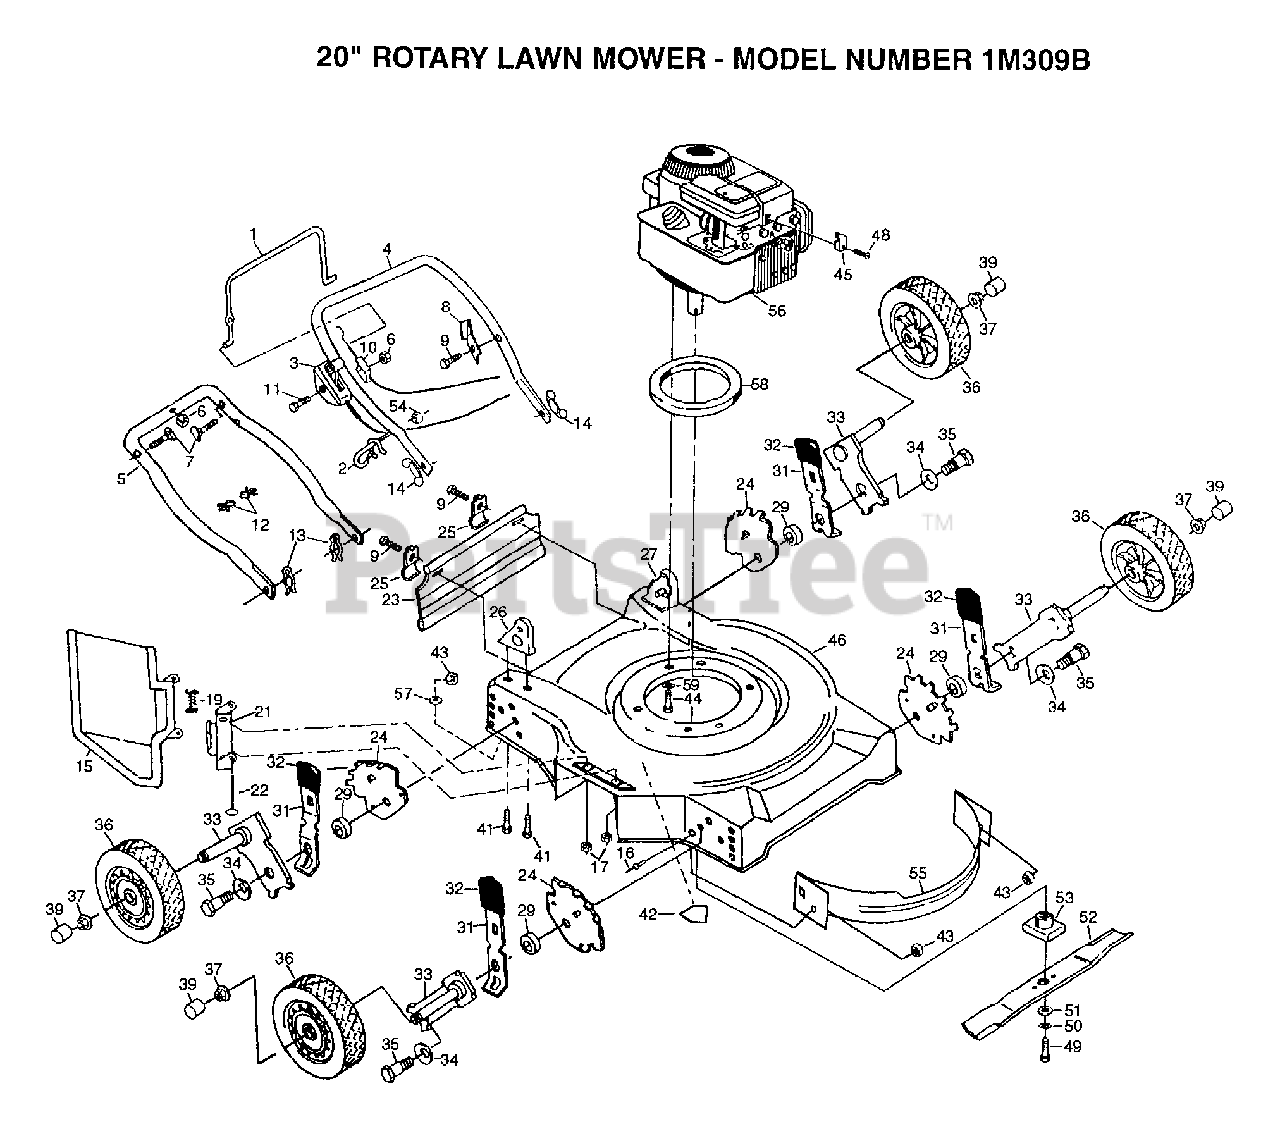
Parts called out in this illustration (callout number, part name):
1	CONTROL BAR PM
2	ROPE GUIDE
3	"CONTROL, THROTTLE"
7	BOLT.HANDLE.LM
8	"BRKT,UPSTOP"
9	TAPPING SCREW
10	CABLE.ASM
11	SCREW.HXHD.WASH.
13	HAIRPIN COTTER
14	"NUT,WING PM"
15	"GRD,DISCHARGE"
16	BLIND RIVET
19	"SPRING,TORSION"
21	HINGE DEFLECTOR
22	HINGE ROD
23	SKIRT.RD.20/22
24	BRACKET.ADJ.9POS.
25	"BRKT,DEFL PM"
26	HDLE BRKT ASSY.RH
27	HDLE BRKT ASSY LH
29	SPACER.HEIGHT.ADJ
31	SPRING SELECTOR
32	KNOB PM
33	ARM.AXLE.ASM.BZP.
34	"WASHER, BELLEVIL."
35	BOLT SHLD 3/8-16
36	WHEEL&TIRE
37	HEX FLANGE LOCKNT
39	HUB CAP-PLASTIC
41	SCREW 5/16-18X3/4
42	DECAL HYT
43	LOCKNUT PM
44	SCREW
45	CABLE CLAMP
46	HOUSING KIT MOWER
48	SCREW PM
49	SCREW
50	LOCKWASHER
51	"WASHER,HARDEN"
52	BLADE.20.MULCH.AY
53	ADAPTOR.BLADE.LM
54	NUT
58	ENGINE SPACER
